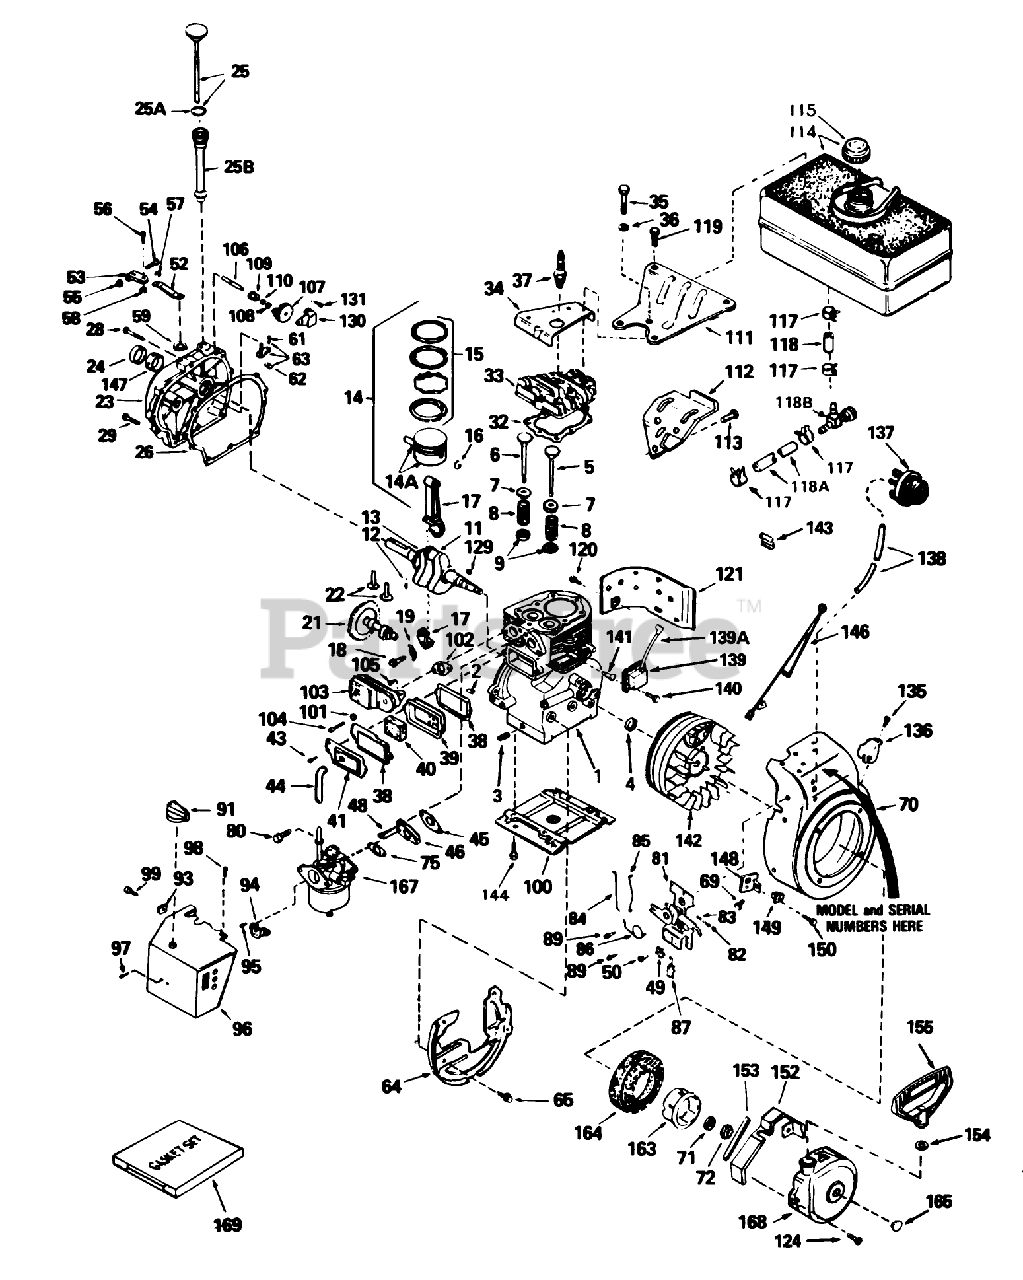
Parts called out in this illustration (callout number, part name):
1	Cylinder Assy. (Incl. Ref. #2, 3 4)
2	Pin-Dowel
3	Plug-Drain, Oil (SQH 1/4-18)
4	Oil Seal
5	Valve, Intake (Standard)(Incl. No. 9)
5	Valve, Intake (1/32" oversize)(Incl. No. 9)
6	Valve, Exhaust (Standard)(Incl. No. 9)
6	Valve, Exhaust (1/32" oversize)(Incl. No. 9)
7	Cap-Spring, Valve
8	Spring-Valve
9	Keeper-Spring, Valve
11	Crankshaft Assy. (Incl. Ref. #12 13)
12	Pin, Groove
13	Gear-Crankshaft
14	Piston, Pin Ring Assy. (Std.) (Incl. Ref. #19A, 20 21)
14	Piston, Pin Ring Assy. (.010 oversize) (Incl. Ref. #19A, 20 21 )
14	Piston, Pin Ring Assy. (.020 oversize) (Incl. Ref. #19A, 20 21)
14A	Piston Pin Assy. (Std.) (Incl. Ref. #20)
14A	Piston Pin Assy. (.010 oversize) (Incl. Ref. #20)
14A	Piston Pin Assy-. (.020 oversize) (Incl. Ref. #20)
15	ORing
15	Ring Set (.010" OS)
15	Ring Set (.020" OS)
17	Rod Assy., Connecting (Incl. Nos. 10 18)
18	Bolt, Connecting Rod
19	Dipper-Oil
21	Camshaft
22	Lifter-Valve
23	Cover, Cylinder (Incl. Nos. 24 106)
24	Oil Seal
25	Dipstick, Oil (Incl. Ref. #88)
25A	O-Ring
25B	Tube Fill
26	Gasket-Cover, Cylinder
28	Screw (1/4-20 x 1-1/4)
29	Screw
32	Gasket-Cylinder Head
33	CYLINDER HEAD
34	Cover-Head, Cylinder
35	Screw (5/16-18 X 2-1/2)
36	Washer-Flat
37	Plug, Spark (J17LM or equiv.)
37	Plug, Spark (Champion RCJ-8)
38	Gasket-Breather
39	Body-Breather
40	Element-Breather
41	Cover-Valve
43	Screw
44	Tube-Breather
45	Gasket-Intake
46	481-1279 SENATOR RO
48	Screw
49	Conduit
50	Screw (10-32 x 3/8)
52	Lever-Governor
53	Clamp-Lever, Governor
54	Screw
55	Nut-Lock
56	Screw
57	Washer-Lock
58	Nut-Lock
59	Ring-Retaining
61	Screw (6-40x5/16)
62	Yoke-Governor
63	Rod, Governor (Incl. Nos.62 63)
64	Baffle Blower Housing
65	Screw (1/4-20x19/32)
69	Screw
70	Housing, Blower (Incl. Ref. #135 136)
71	Washer-Belleville
72	Flywheel Nut
75	Gasket-Carburetor
80	Screw-Hex Hd.
81	Control Assy., Remote Speed (Incl. Ref. #90 thru 93)
82	Screw
83	Spring-Compression
84	Governor Link
85	Link-Throttle
86	Spring-Throttle
87	Terminal
89	Screw (10-32 x 1/2)
91	Knob-Control
93	Nut-U Type
94	Bracket-Choke
95	Screw (10-32 x 1/2)
96	Carburetor Cover
97	Screw (8-32 X 5/16)
98	Screw (10-32x1/2)
99	Screw (8-32 x 3/8)
100	Base Engine
101	Washer
102	Gasket Exhaust
103	Muffler
104	Screw (5/16-18 X 2)
105	Screw
106	Shaft-Governor
107	Governor Gear ASM
108	Ring-Retaining
109	Spool-Governor
110	Washer-Flat
111	Bracket-Fuel Tank
112	Bracket-Fuel Tank
113	Screw (1/4-20x19/32)
114	Tank Assy., Fuel (Incl. Ref. #115)
115	Cap, Fuel
117	Clamp-Line, Fuel
118	Line-Fuel
118A	Line-Fuel (8.62)
118B	Valve-Shut Off
119	Screw (1/4-15x7/8)
120	Screw
121	Extension-Blower Hsng.
124	Screw
129	Key-Flywheel
130	Bracket, Governor
131	Screw (10-24x1/2)
135	Screw (8-32 x 3/8)
136	Screw
137	Primer Assy.
138	Line-Primer
139	Solid State
139A	Cover-Spark Plug
140	Screw
142	Flywheel
143	Clip-Wire
144	Screw
146	Ground Wire
147	Bushing-Crankshaft
148	Bracket
149	Grommet
150	Screw
152	Guard-Starter
153	Seal, Snowguard
154	Washer
155	Handle-Starter, Mitten Grip
163	Cup-Starter
164	Screen-Starter
165	Plug-Starter
167	Carburetor (Incl. Ref. #75)
168	Starter-Rewind
169	Gasket Set
